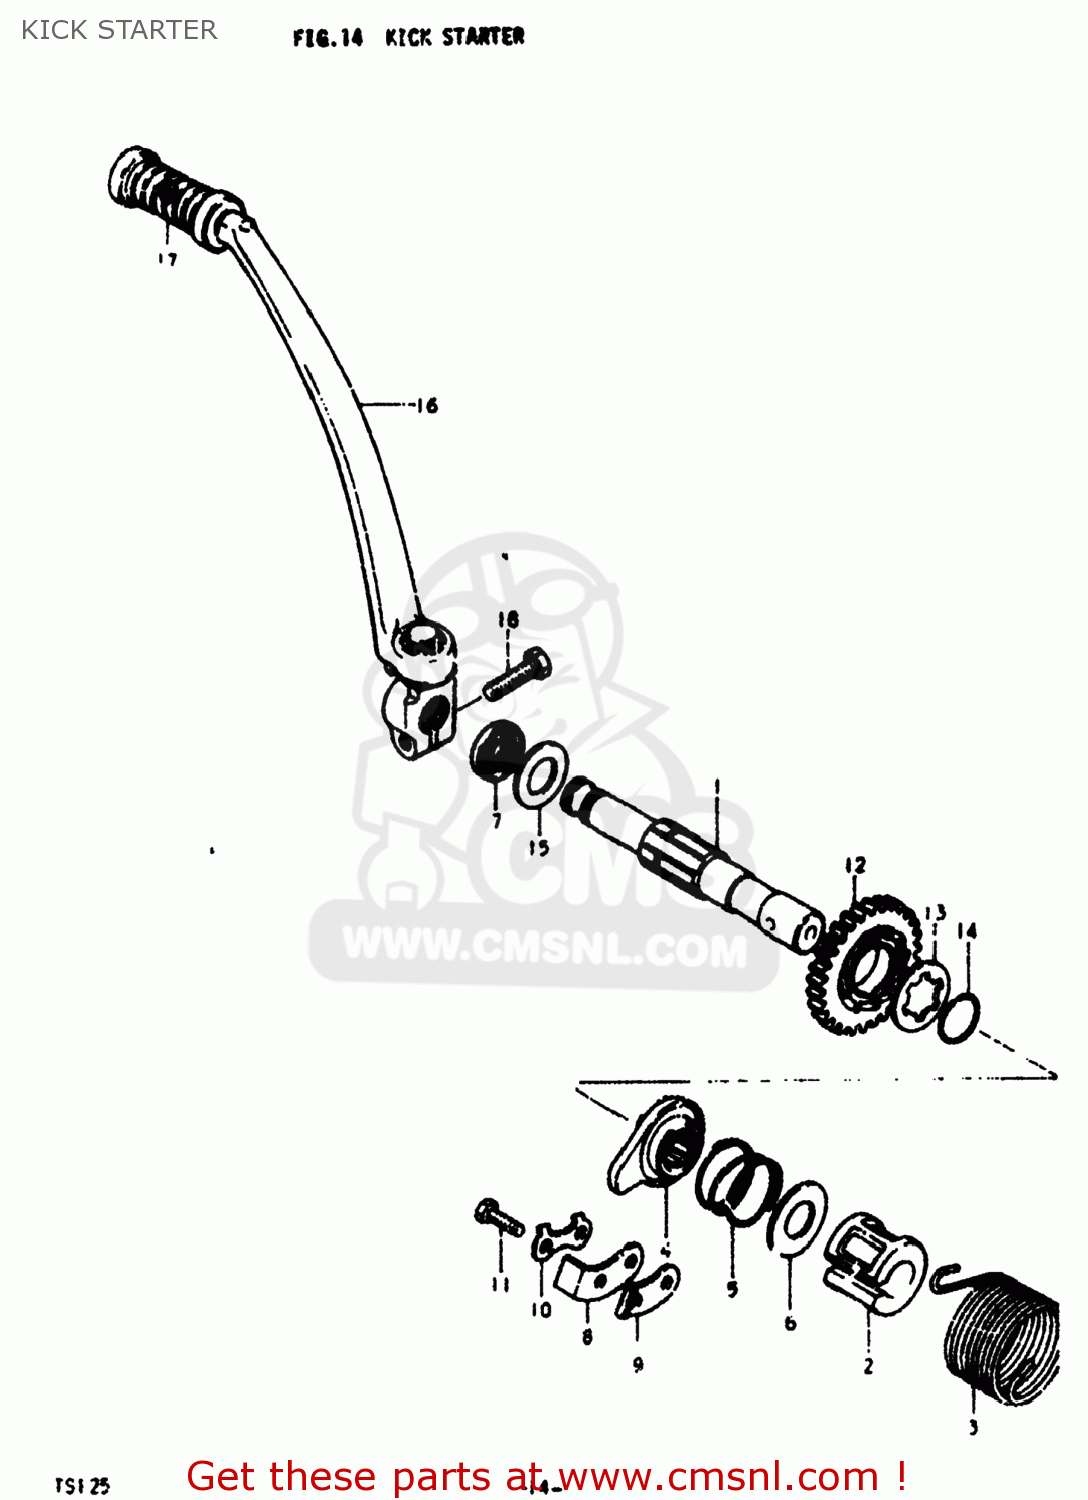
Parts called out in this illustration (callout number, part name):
1	SHAFT,KICK STARTER
2	GUIDE,KICK STARTER SFT SPRING
3	SPRING
4	STARTER,KICK
5	SPRING
6	WASHER
7	SEAL,OIL(16X30X8)
8	GUIDE,KICK STARTER
9	STOPPER,KICK STARTER
10	WASHER
11	BOLT, UPPER
12	GEAR,KICK STARTER DRIVE
13	WASHER,LOCK
14	CIRCLIP
15	WASHER(16X30X1)
16	LEVER ASSEMBLY,KICK STARTER
17	RUBBER,KICK STARTER PEDAL
18	BOLT
